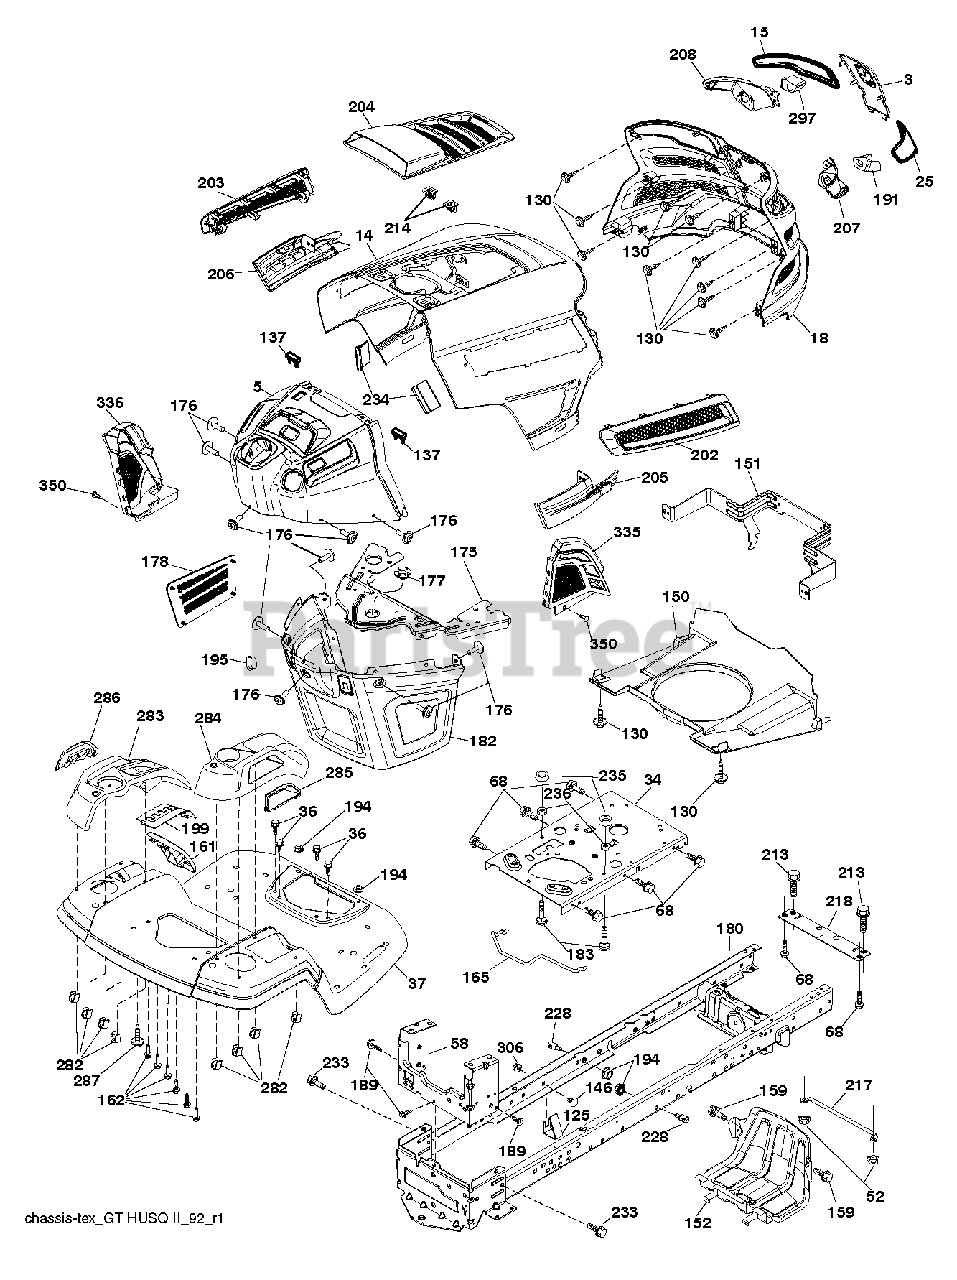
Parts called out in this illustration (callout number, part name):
3	APPLIQUE.SUBASM.GT.HUSQ.II
5	DASH
14	HOOD.ASM.HUSQVARNA.GT.TEX.ORAN
15	LENS.HEADLIGHT.LH.GTII.2011
18	GRILLE.SUBSTRATE.2011.
25	LENS.HEADLIGHT.RH.GTII.2011
34	PLATE.ENGINE.WELDED.CHASSIS
36	SCREW 5/16"
37	FENDER.TLT.FS.W/CPH/FW/RSF.668
52	LOCKNUT
58	DRAWBAR UPPER 2PC SMALL FENDER
68	SCREW LT
125	CLIP.FUEL.LINE
130	SCREW.#10 X 0.750.BOS
137	BUMPER DASH
146	BOLT.RDHD.SHT.SQNK.3/8-16X5/8
150	AIR.DUCT.GTV.BLACK
151	BRACKET.PIVOT.HOOD.GT.HUSQ.II
152	SHIELD.BROWNING.PNT.GT.V2
159	SCREW, 3/8-16X3/4
161	WINDOW.FUEL.LT.HUSQ.TEX.498
162	SCREW.HI-LO.CONSOLE
165	SUPPORT.TANK.REAR.W/TEX
175	PLATE.CROSSMEMBER.HUSQ
176	SCREW.#10-24X5/8.RN.QU
177	BUSHING, STEERING
178	CARGO.ASM.NET.TXGT.W/C
180	CHASS.WLDMNT.TL.12GA/2P.48/54
182	DASH.LOWER.COMMON.12V.ADAPTOR
183	BOLT.5/16-18X1-1/4 FULL THD
189	SCREW
191	INSERT.REFLECTIVE.RH.HUSQ.GTII
194	NUT LOCK HEX FLANGE 5/16-18
195	PLUG.HOLE.DASH.LOWER.12V.BLK
199	PLATE.DECK.LIFT.HUSQ.LT
202	VENT.SIDE.RH.GT.HUSQ.II.
203	VENT.SIDE.LH.GT.HUSQ.II.498
204	VENT.TOP.HUSQ.GT2
205	SIDE.TRIM.RH.GT.HUSQ.II
206	BRACKET.MOUNT.CRUISE.LATCH
207	BEZEL LIGHT.RH.GT.II.MYLAR
208	BEZEL LIGHT.LH.GT.II.MYLAR
213	BOLT
214	CLIP.RETAINER.TINNER.
217	ROD.PIVOT.HOOD
218	X-PIECE.HOOD.STOP.NON/
228	STUD.FASTNER.W/ANTI-ROTATE
233	BOLT.SHOULDER
234	BUMPER.HOOD.TEX.HUSQVARNA
235	SPACER FENDER
236	NUT.CENTERLOCK.5/16-
282	CLIP.RETAINER.CONSOLE.LT.HUSQ
283	CONSOLE.DECK.LIFT.R.SDFL.HUSQ
284	CONCOLE.CNTRL.PDL.HUSQ.LT.498
285	CONSOLE INSERT RH
286	CONSOLE.INSRT.LH.HUSQ.LT.BLACK
287	SCREW 1/4X20
297	INSERT.REFLECTIVE.LH.HUSQ.GTII
306	NUT LOCK FLG 3/8-16 UNC
335	COVER.LOWER.DASH.RH.BLACK
336	COVER-LH.LOWER.DASH.GT2.BLACK
350	CLIP.X-MAS.TREE
